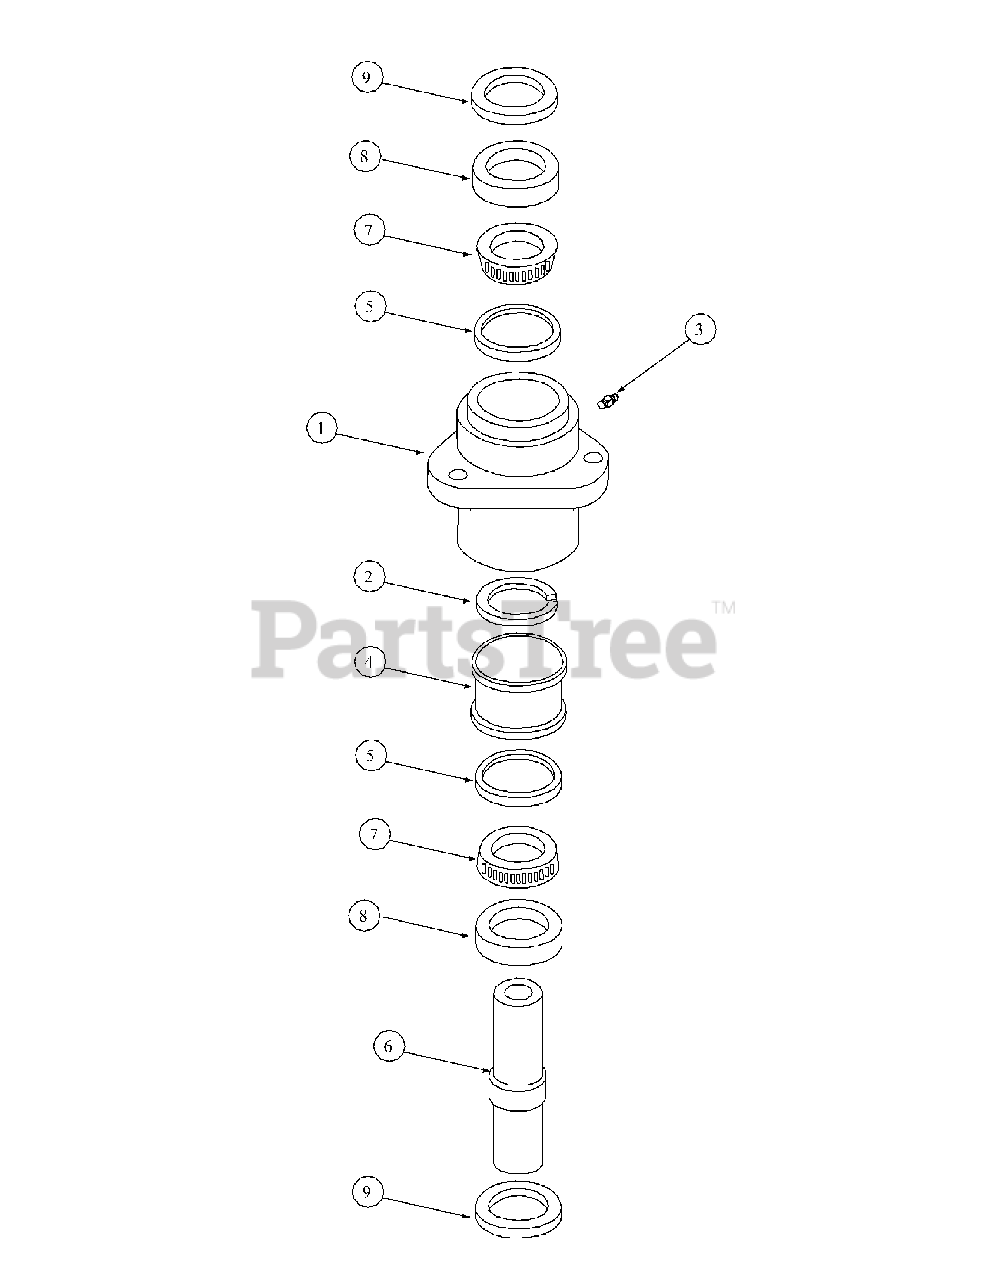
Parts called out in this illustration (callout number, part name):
1	Spindle Housing
2	Spacer Bearing
3	Grease Fitting
4	Spacer
5	Cup Bearing
6	Shaft Blade Spindle
7	Cone Bearing
8	Ring Seal
9	Oil Seal
